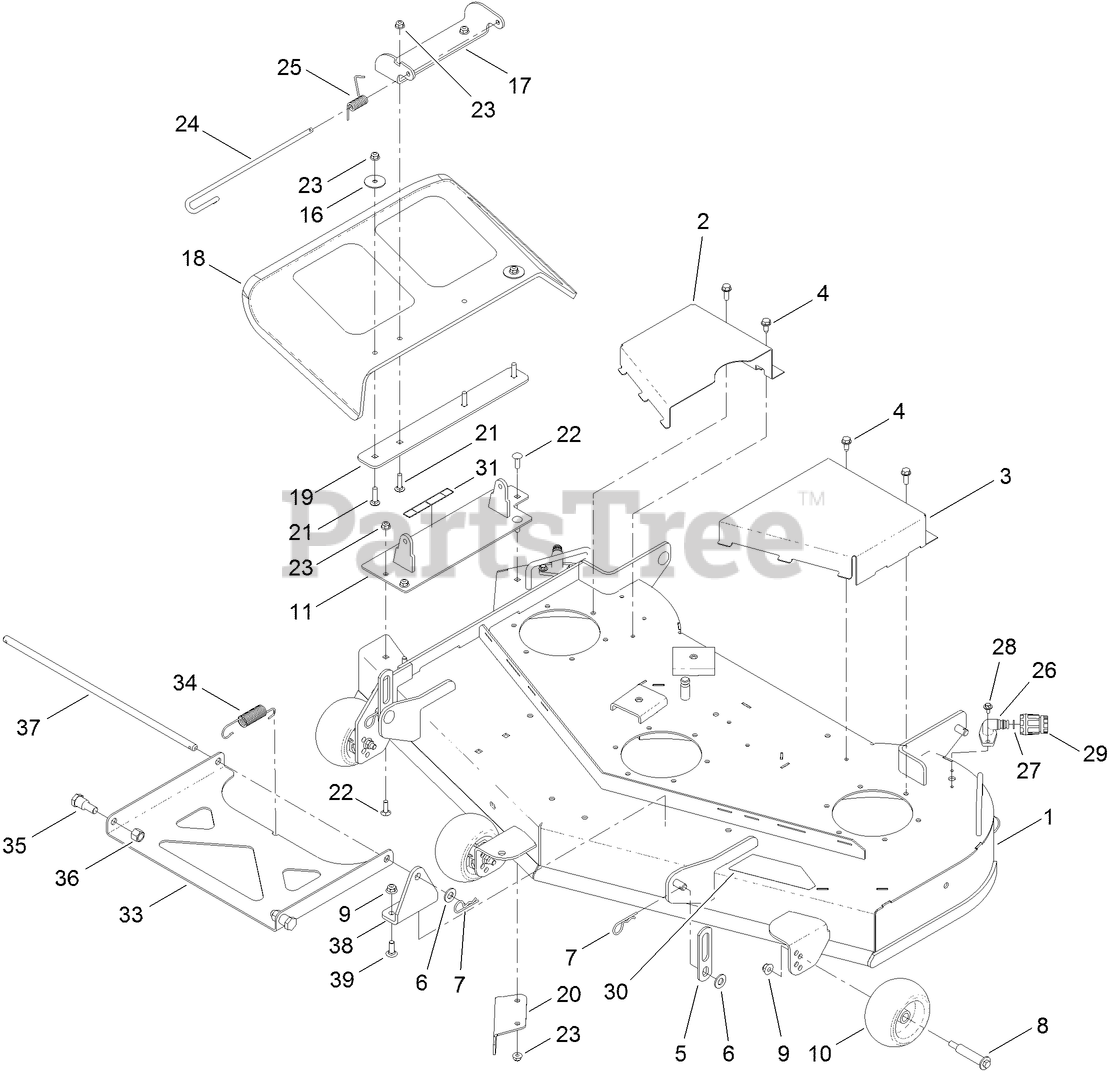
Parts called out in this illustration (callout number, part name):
1	48 INCH DECK AND DECAL ASM
4	SCREW-HWHTF
5	LINK-LIFT
6	WASHER-FLAT
7	PIN-COTTER
8	BOLT-SHOULDER
9	NUT-HF, NI
10	ROLLER-SCALP, ANTI
16	WASHER-FLAT
17	BRACKET-DEFLECTOR, UPPER
18	DEFLECTOR
19	PLATE-DEFLECTOR
20	BAFFLE-CUTOFF
21	SCREW-CARR
22	SCREW-CARR
23	NUT-HF, NI
24	PIN-CHUTE
25	SPRING-TORSION
27	O-RING
28	SCREW-HHFTF
29	CONNECTOR-HOSE
30	DECAL-DECK
31	DECAL-DANGER
33	PAN-PIVOT, DECK
34	SPRING-EXTENSION
36	NUT-LOCK, NI
37	ROD-DECK, PIVOT
38	BRACKET-PIVOT, FRONT
39	SCREW-CARR
